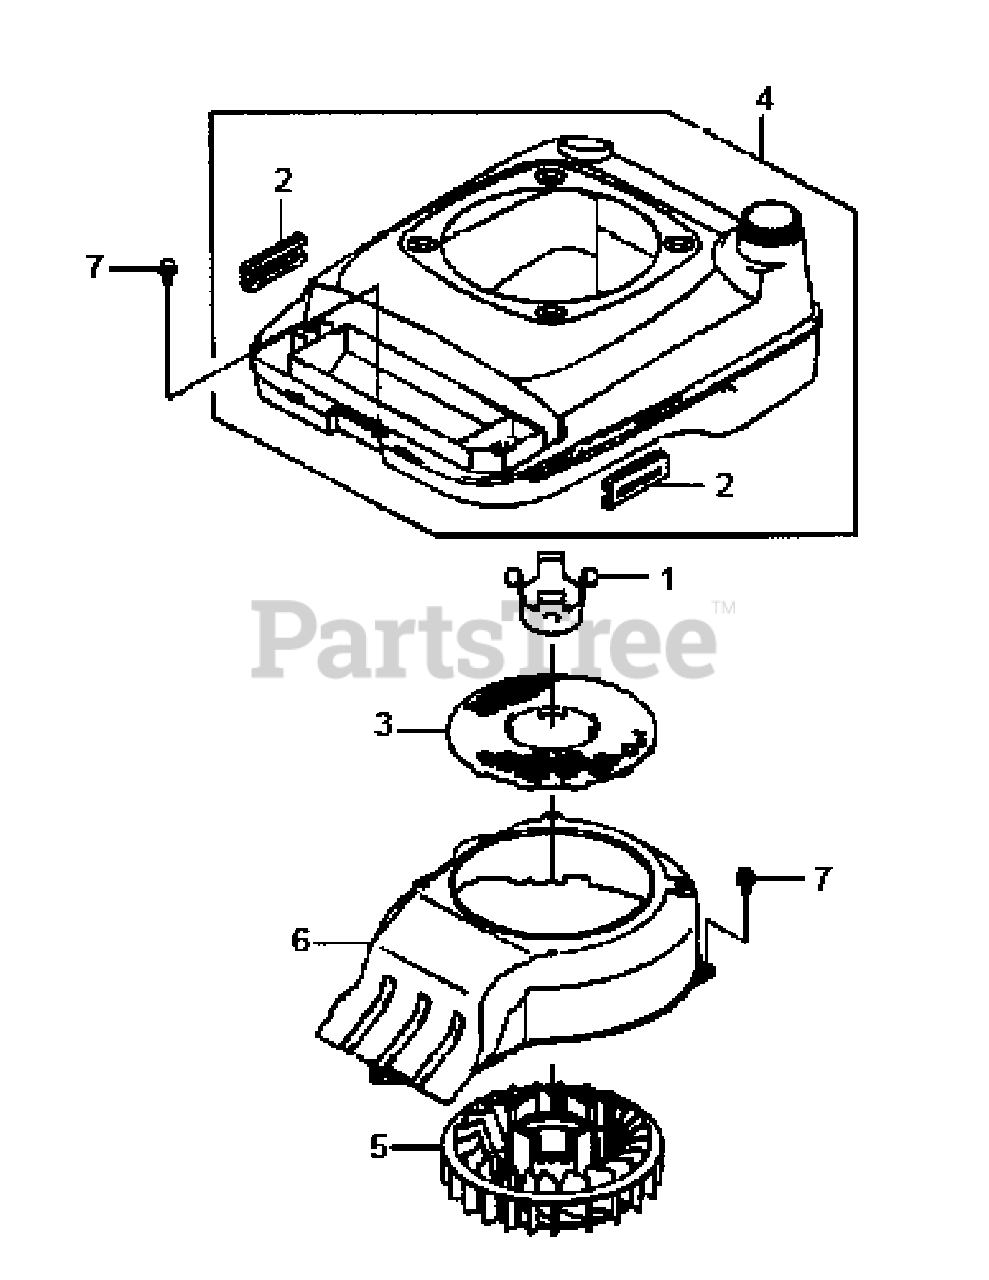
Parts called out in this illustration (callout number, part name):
3	Screen
4	Cover
5	Fan
6	Fan Housing
7	Flanged Bolt
